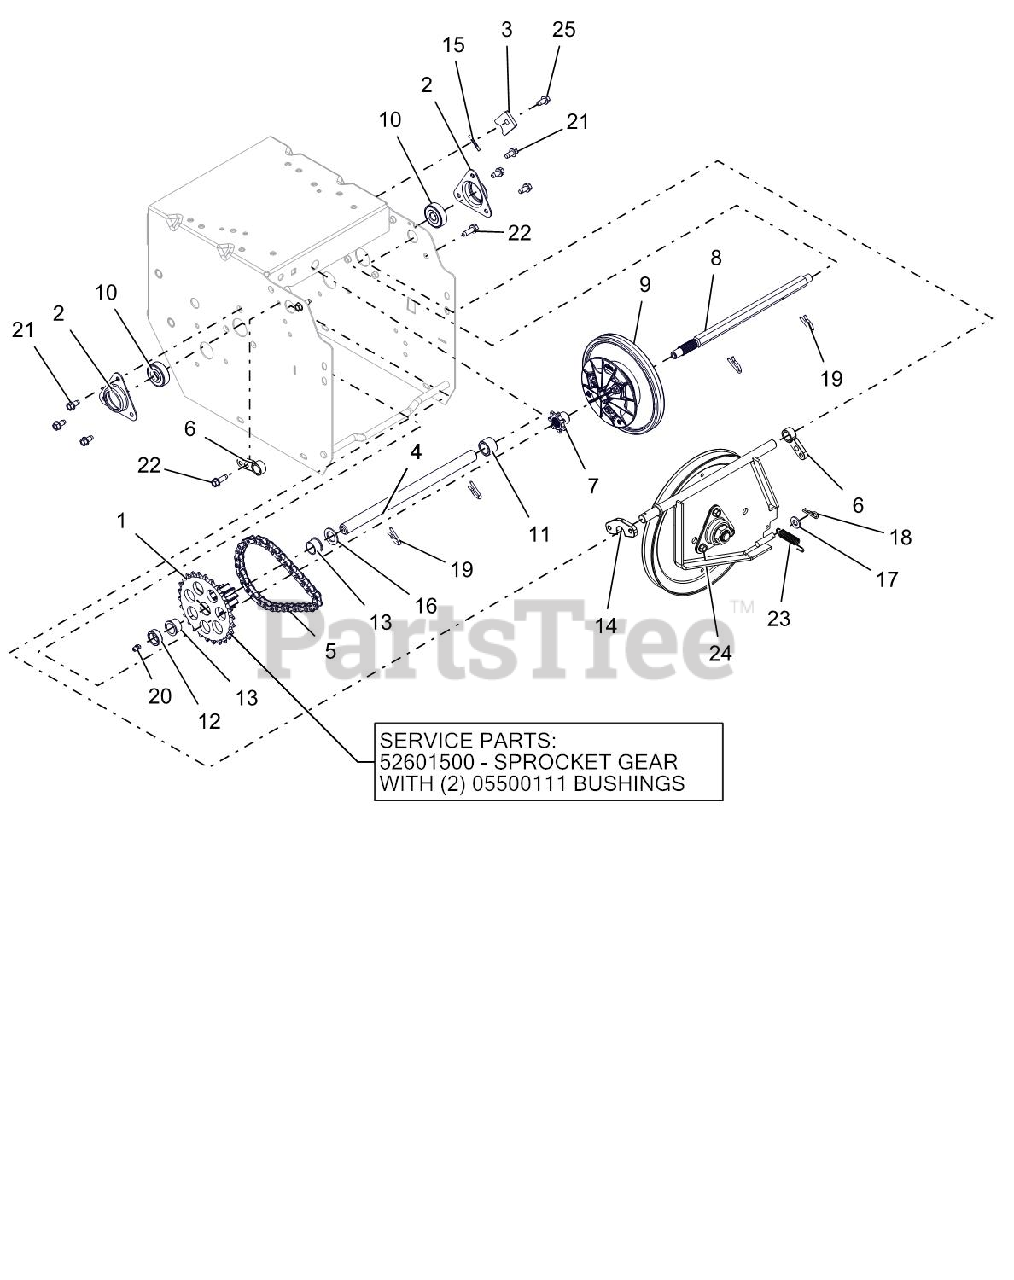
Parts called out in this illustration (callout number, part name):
1	BSHG-FLG .625X.750X.500X.875
1	PINION & SPROCKET
1	PINION & SPROCKET W/BUSHINGS
2	FLANGE, BEARING
3	TAB, ANTI ROTATION
4	SHAFT, PINION
5	CHAIN - #41, 32 PITCHES
6	SUPPORT BUSHING, SWING GATE
7	SPROCKET, PINION 7T W/SPLINE
8	SHAFT, HEX W/SPLINE
9	DISC, FRICTION DRIVE-ASSEMBLY
10	BRG-BALL .437X1.375X.437
11	SPACER, .635X.880X.611
12	BSHG-SLV, .635X.880X.305
13	BSHG-FLG .625X.750X.500X.875
14	SPACER, SWING GATE
15	PIN-GRV .125X1.00 TP E ALLOY
16	WSHR-FL-STL .630X1.005X.062 YZ
17	WSHR-FL-STL.344X.688X.065YWZC
18	PIN-HAIR INT .08X.18X1.18 YWZC
19	PIN, SPRING CLIP
20	ZERK,FITTING .25X.125 DRIVE IN
21	SCR-TAP .25-20X.50 HWH TR YWZ
22	SCR-TAP-PM .25-20X.75 TR YWZ
23	SPRING, EXT. .043X.438X1.64
24	PLATE, SWING - ASSEMBLY
25	SCR-TAP .25-20X.50 HWH TR YWZ
